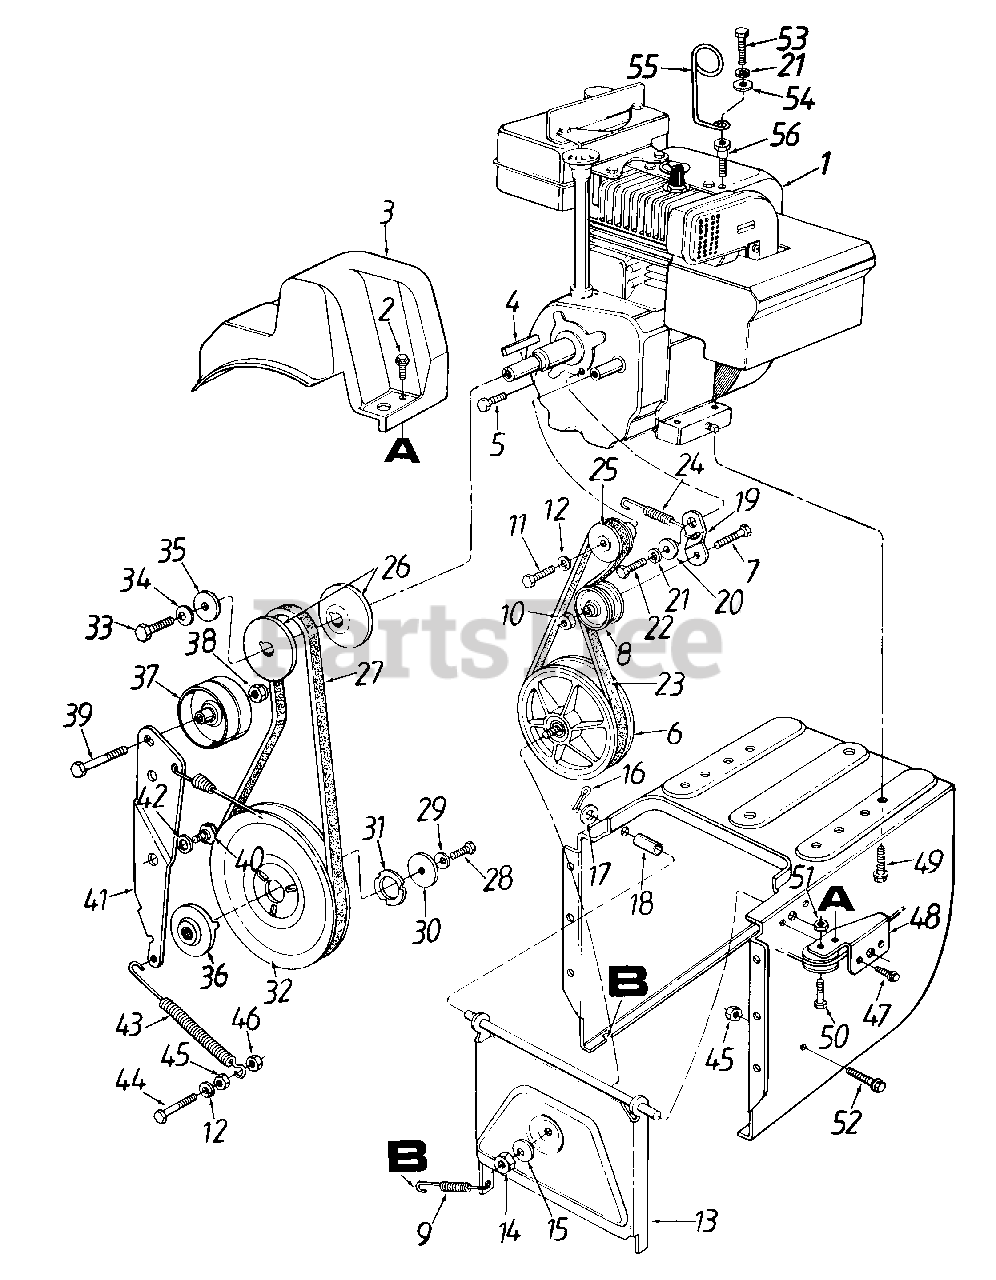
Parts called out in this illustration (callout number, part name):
1	Engine
2	Hex Wash. Hd. TT-Tap Scr. 1/4-20 x .5" Lg.
3	Belt Cover
4	Sq.-Key 3/16 x .75" Lg.
5	Hex Patch Bolt 5/16-24 x 1" Lg. (Gr.5)
6	Friction Wheel Disc Ass'y.
7	Hex Bolt 3/8-16 x 1.25" Lg.
8	Fl-Idler 2.12" O.D.
9	Ext. Spring 2.5" Lg.
10	Hex Top L-Nut 3/8-16 Thd.
11	Hex Bolt 1/4-28 x .5" Lg.
12	L-Wash. 1/4" I.D.
15	Bell-Wash. .38" I.D. x .88" O.D.
16	Cotter Pin 1/8" x .75" Lg.
17	Fl-Wash. .531" I.D. x .93" O.D.
18	Spacer .508" I.D. x .75" O.D.
19	Drive Clutch Idler Bracket
20	Shld. Spacer .5" Dia. x .27" Lg.
21	L-Wash. 5/16" I.D.
22	Hex Bolt 5/16-24 x 1" Lg.
23	"V"-Belt
24	Extension Spring
25	2" Dia. Pulley
26	3/8 "V"-Pulley Half
27	"V"-Belt
28	Hex Cap L-Bolt 5/16-24 x .75" Lg.
29	Bell-Wash. .345" I.D. x .88" O.D.
30	Fl-Wash. .34" I.D. x 1.5" O.D.
31	Brg. Retaining Washer
32	Auger Pulley
33	Hex Bolt 3/8-24 x .88" Lg.
34	Bell-Wash. .39" I.D. x 1.13" O.D.
35	Fl-Wash. .406" I.D. x 1.25" O.D.
36	Adapter Pulley
37	Fl-Idler 2.75" O.D.
38	Hex Ins. L-Nut 3/8-24 Thd.
39	Hex Bolt 3/8-24 x 1.5" Lg. (Gr. 5)
40	Shld. Bolt .625" Dia. x .170" Lg.
42	Wave Wash. .66" I.D. x .88"
43	Ext. Spring 3.6" Lg.
44	Hex Bolt 1/4-20 x .75" Lg. (Gr. 5)
45	Hex Nut 1/4-20 Thd.
46	Hex L-Nut 1/4-20 Thd.
47	Torx Mach. AB-Tap Scr. 1/4 x .62" Lg.
50	Shld. Bolt 5/16" Dia. x .35" Lg.
51	Hex Jam Nut 1/4-20 Thd.
52	Hex Wash. Hd. TT-Tap Scr. 1/4-20 x 1" Lg.
53	Hex Bolt 5/16-18 x 5/8" Lg.
54	Fl-Wash. .349" I.D. x .879" O.D.
55	Cable Control Wire
56	Engine Stud
